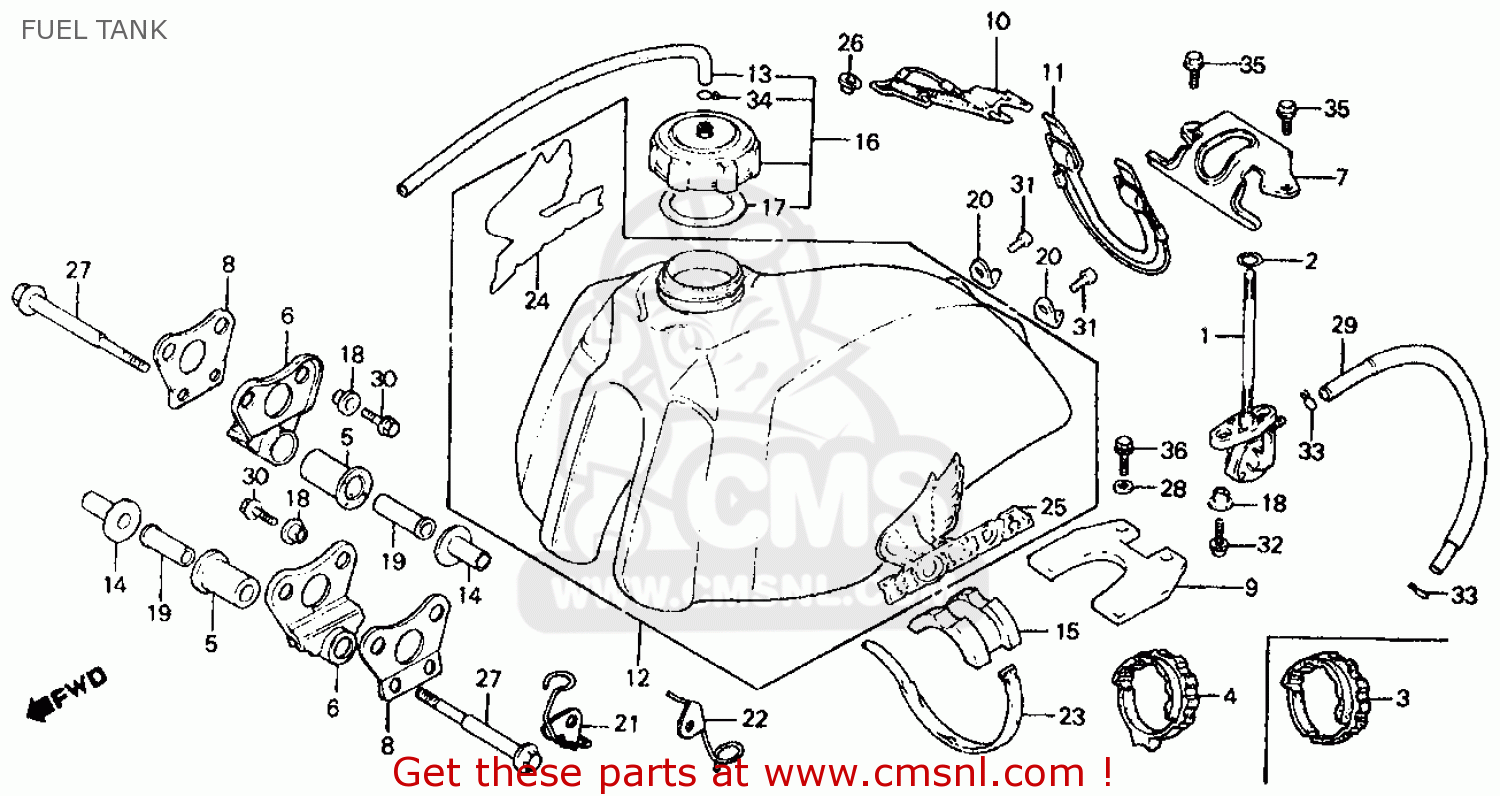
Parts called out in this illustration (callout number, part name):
1	COCK ASSY,FUEL
2	O-RING,11.8X3.55
5	RUB,FUELTANK MTG.
6	BRACKET,TANK.MOUN
7	STAY,RR.FUEL TANK
8	RUB.,FR.TANK MTG.
9	RUB.,RR.TANK MTG.
11	BAND,RR.TANK
12	TANK SUB,FUEL
13	TUBE,FUELCAP BRTH
14	COLLAR,TANK.MOUNT
15	CUSHION,FR.TANK
16	CAP,FUEL TANK
17	PKG,FUEL TANK CAP
18	COLLAR TANK SETT
19	COLLAR,SLIDER
20	HOOK,TANK RR.
23	BAND,WIRE
24	MARK,R.FUEL TANK
25	MARK,L.FUEL TANK
27	BOLT FUELTANK MTG
28	WASHER,SPRKT SETT
29	TUBE,FUEL,5.3X240
30	BOLT,HEX 6X16
31	SCREW,PAN,6X12
32	SCREW-WASH,6X20
34	CLIP,TUBE 5.0MM
35	BOLT FLANGE 6X14
36	BOLT,FLANG,6X16
